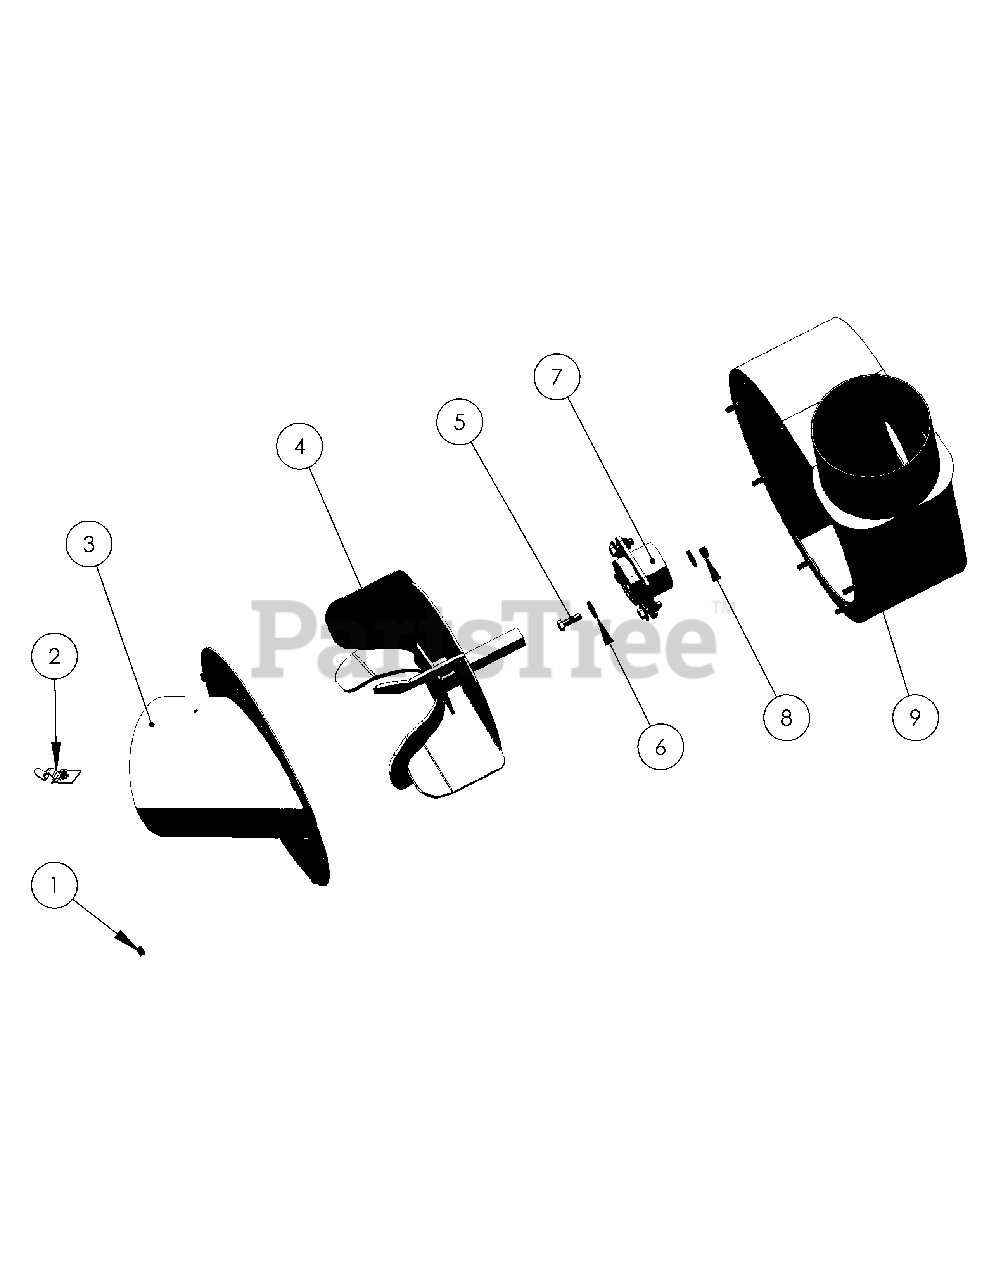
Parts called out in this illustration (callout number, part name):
1	1/4" X 20 Nylock Nut
2	Hose Clamp
3	7" Blower Inlet
4	Blower Impeller
5	5/16 - 18 X 1" Bolt
6	5/16 Washer
7	Repairable Bearing
8	5/16 Nut
9	Blower Housing
